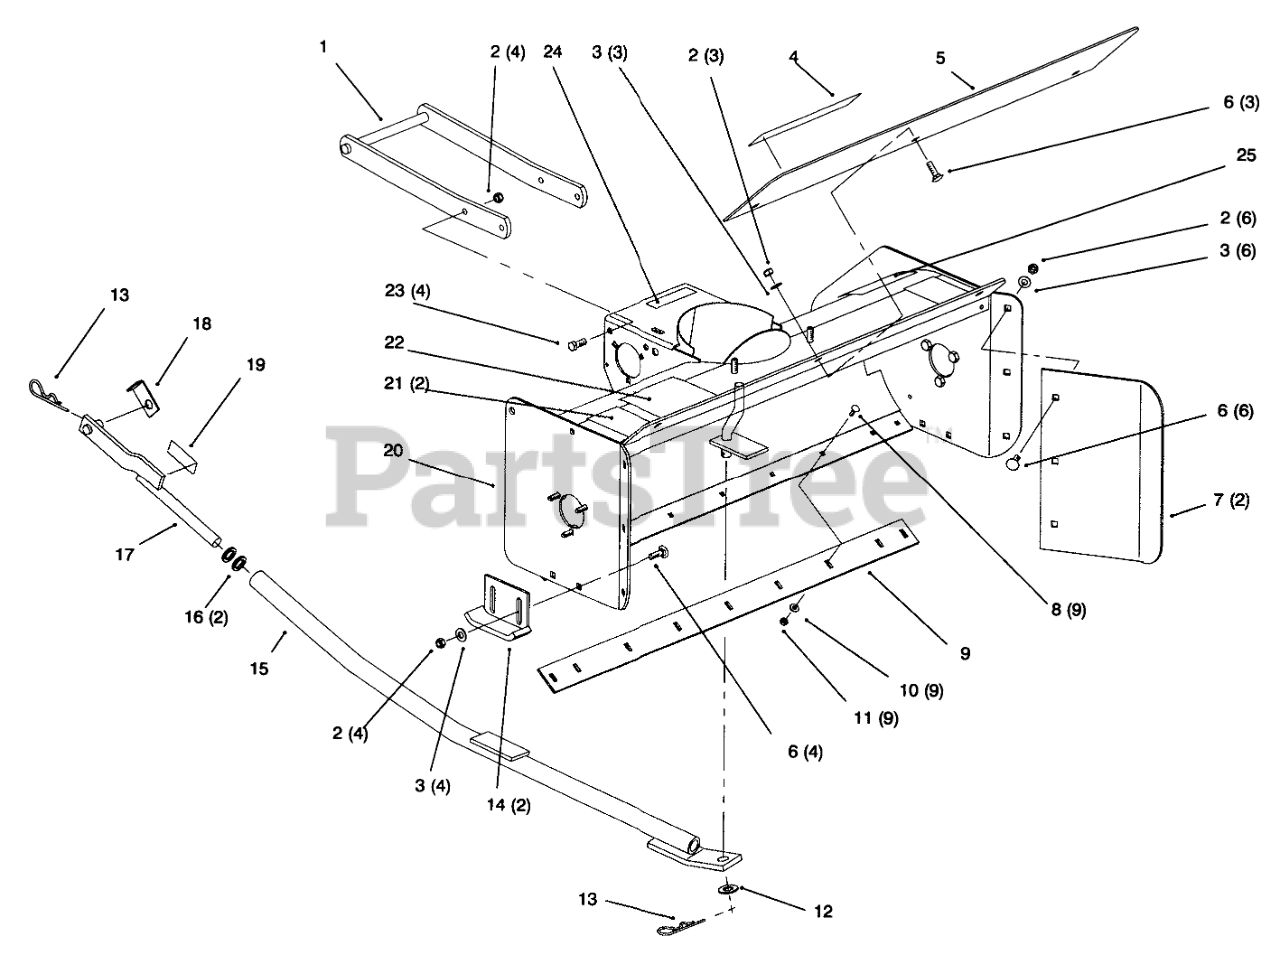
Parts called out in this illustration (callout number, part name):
2	NUT-LOCK, NI
3	WASHER-FLAT
4	DECAL-ATTACHMENT
5	PLATE-EXTENSION
6	BOLT-CARR
7	PLATE-EXTENSION, RH
8	SCREW-CARR
9	SCRAPER-REVERSIBLE
10	WASHER-FLAT
11	NUT-LOCK, NI
12	WASHER-FLAT
13	PIN-COTTER, HAIR
15	LIFT ROD
16	Washer
17	WLDMT-LIFT ROD BLK
17	CROSS REFERENCE TO 92-9778
18	RETAINER CLIP
19	DECAL - WARNING
20	OBS WRAPPER WA W/DECALS RED
21	DECAL-DANGER
22	DECAL-WARNING
23	SCREW-HH
25	DECAL - WARNING
